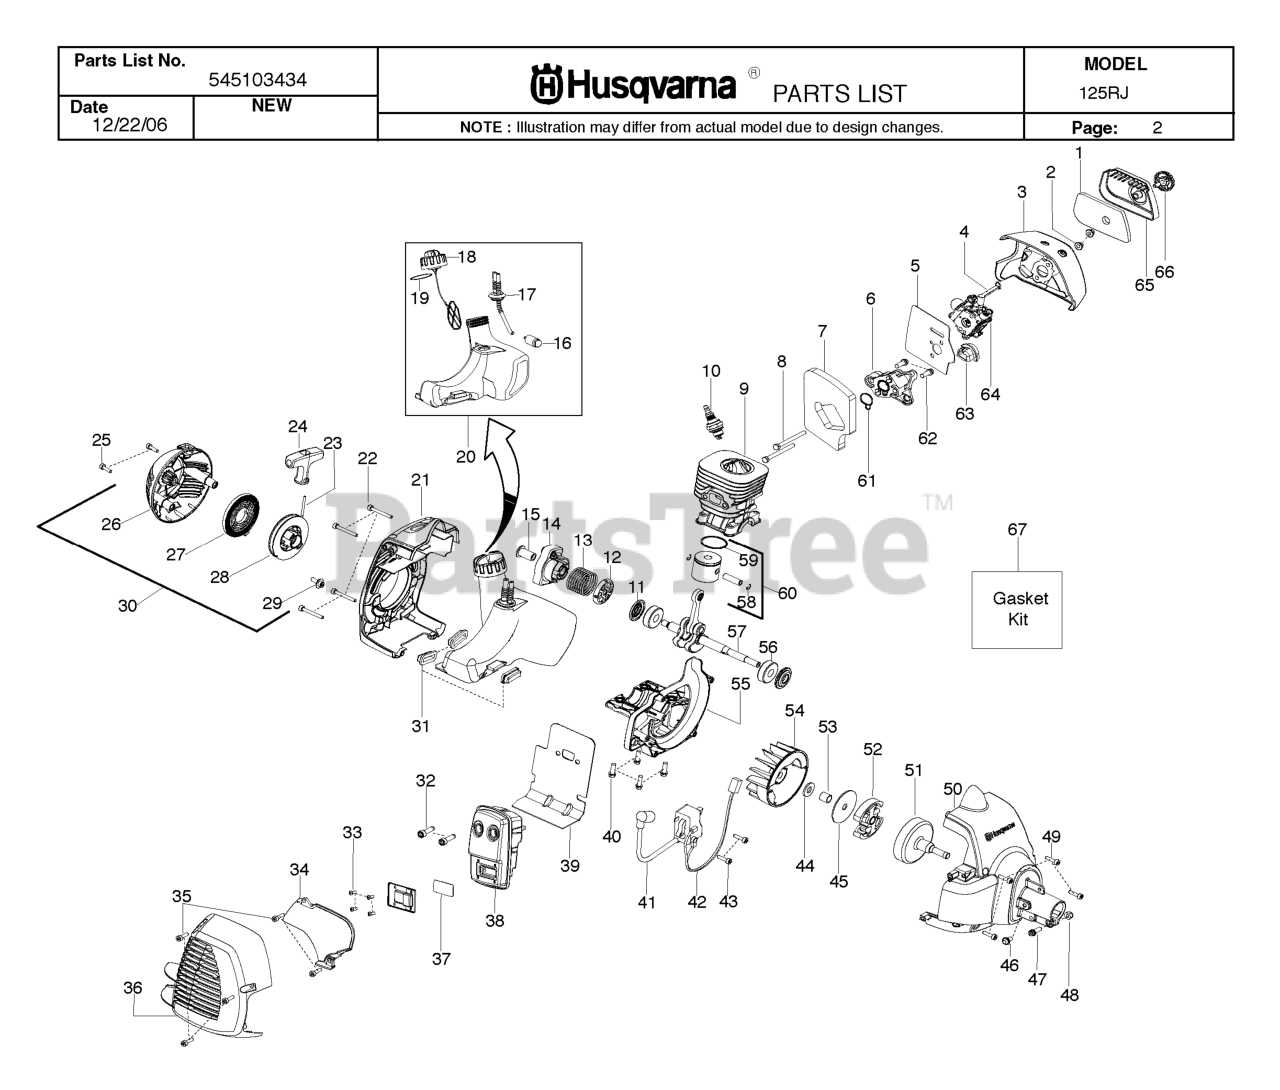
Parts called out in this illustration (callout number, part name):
1	FILTER AIRBOX
3	RP_AIR BOX
4	CHOKE LEVER
5	KIT GASKET CARB
6	CARB ADAPTOR
7	KIT GASKET 28CC TRIMMER
8	BOLT CARB ADAPTOR
9	CYLINDER
10	Plug - Spark (RCJ-8Y)
11	KIT SEAL CRANKSHAFT
12	WASHER STARTER
13	SPRING STARTER CUP
14	ASSY-STARTER CUP
15	COUPLING STARTER
16	FUEL PICK-UP ASSY
17	KIT FUEL LINE
18	ASSY-CAP W/RETAINER
19	O RING NITRILE
20	%FUEL TANK ASSY
21	REAR SHROUD
24	STARTER HANDLE GRAY
25	SCREW M5-0.8X30MM
26	STARTER HOUSING
27	%KIT STARTER SPRING
28	KIT STARTER PULLEY
30	ASSY-STARTER HSG.
31	ISOLATOR FUEL TANK
32	BOLT MUFFLER
33	SCREW-10-16 X 1/2 HI-LO
34	SHIELD HEAT
35	SCREW M4 X 1.75 PT 16MM
36	GUARD-MUFFLER
37	KIT SPARK ARRESTOR SCREEN
38	ASSY MUFFLER NC
39	GASKET PAPER METAL
40	SCREW-M5-0.8 X 25MM(TAP)
41	IGNITION MODULE MBU-7
42	ASSY MODULE LEAD WIRE
43	SCREW M4 X .70 TT 16MM
45	WASHER-CLUTCH
48	NUT HEX LOCK 10-24
49	SCREW M4 X .70 TT 16MM
50	FAN HSG ASSY
51	ASSY-CLUTCH DRUM
52	%KIT CLUTCH ASSY
53	SPACER FLYWHEEL
55	CRANKCASE CASTING
56	BEARING RADIAL BALL (6201)
57	KIT CRANKSHAFT ASSY
58	WRIST PIN RET.
59	RING PISTON
60	KIT PISTON 28CC TRIMMER
61	KIT GASKET 28CC TRIMMER
62	SCREW-M5-0.8 X 25MM(TAP)
65	COVER-AIR BOX
66	KNOB ASSY AIRBOX COVER
67	KIT GASKET 28CC TRIMMER
